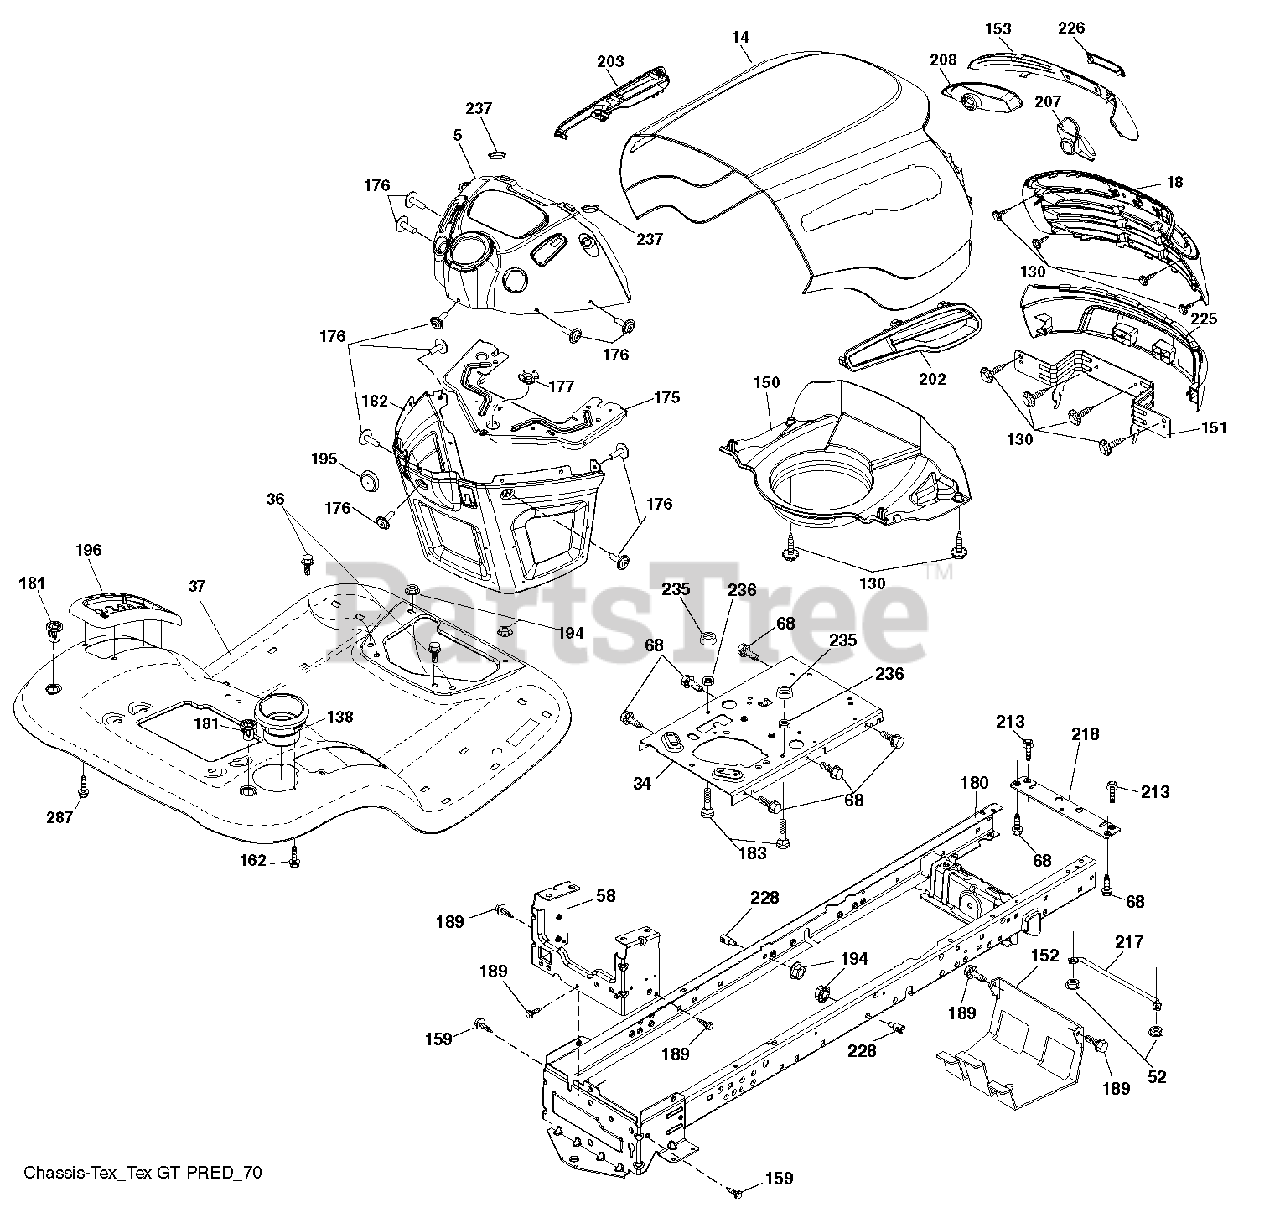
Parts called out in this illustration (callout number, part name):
5	DASH.UPPER.PREDATOR.M/C.BLACK
14	HOOD.PNT.PREDATOR.YT/GT.BLACK
18	GRILLE.SVC.PREDATOR.YT.TEX
34	PLATE.ENGINE.WELDED.CHASSIS
36	SCREW 5/16"
37	FENDER.TLT.W/CPH.428
52	LOCKNUT
58	DRAWBAR UPPER 2PC SMALL FENDER
68	SCREW LT
130	SCREW.#10 X 0.750.BOS (2 2)
138	CUPHOLDER.TL.TEX.BLACK
150	PREDATOR.YT.GT.HOOD.AIR DUCT
151	BRACKET.PIVOT.PREDATOR
152	SHIELD.BROWNING.W/TEX
153	LENS.BAR.PREDATOR.YT.CLEAR
159	SCREW, 3/8-16X3/4
162	SCREW.HI-LO.CONSOLE
175	PLATE.CROSSMEMBER.HUSQ
176	SCREW.#10-24X5/8.RN.QU
177	BUSHING,STEERING
180	CHASS.WLDMNT.TL.12GA/2P.48/54
181	FEND/FTRST.PCH.CPH.NFW
182	DASH LOWER.HUSQ.PRED NO CRUISE
183	BOLT.5/16-18X1-1/4 FULL THD
189	SCREW
194	NUT LOCK HEX FLANGE 5/16-18
195	PLUG.HOLE.DASH.
202	VENT.SIDE.HOOD.RH.PREDATOR.BLK
203	VENT.SIDE.HOOD.LH.PREDATOR.BLK
213	BOLT
217	ROD.PIVOT.HOOD
218	X-PIECE.HOOD.STOP.NON/
228	STUD.FASTNER.W/ANTI-ROTATE
235	SPACER FENDER
236	NUT.CENTERLOCK.5/16-
237	PLUG.MOUNT.CARGO.BLK
287	SCREW 1/4X20
